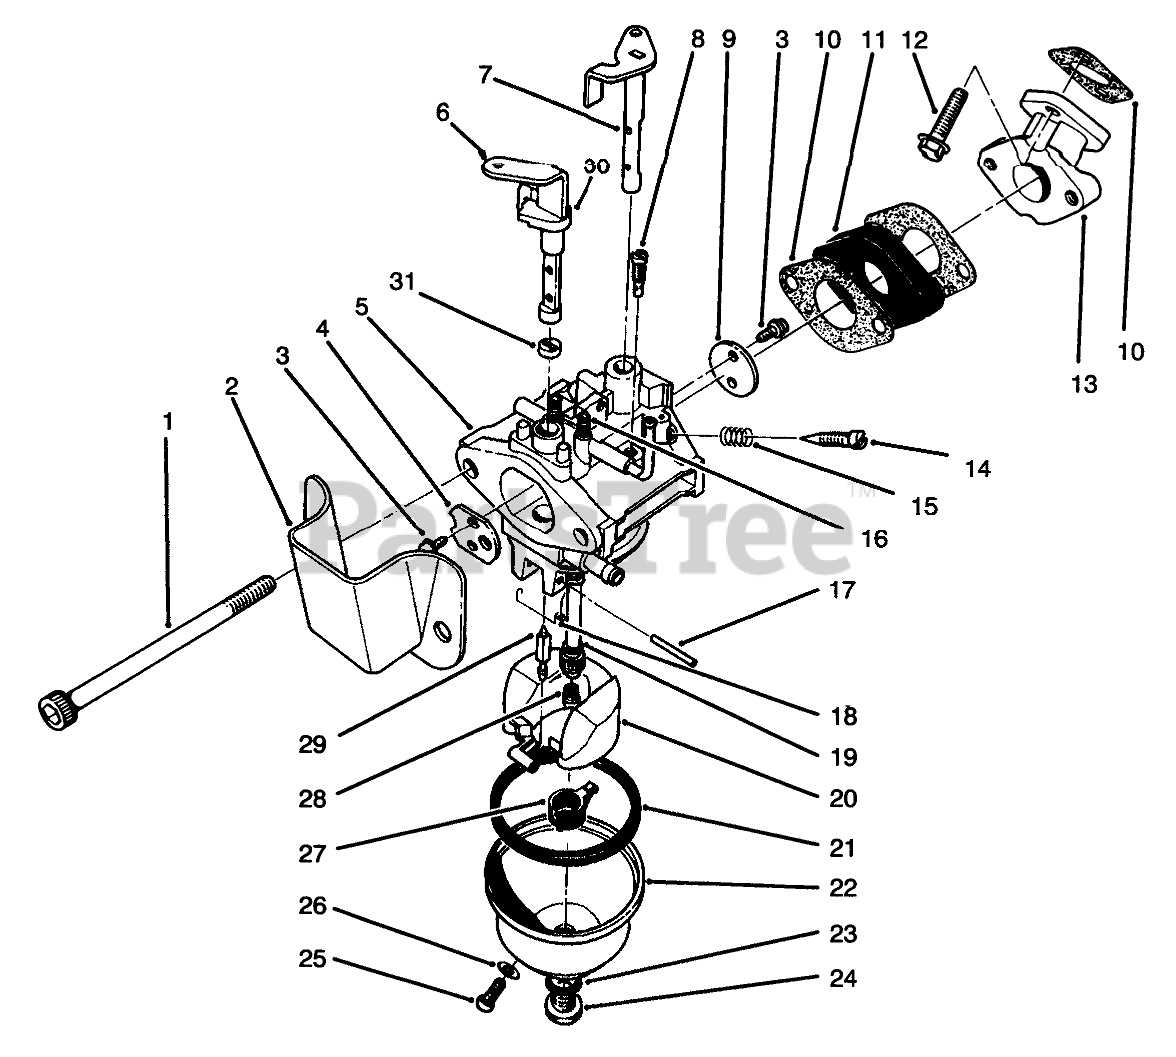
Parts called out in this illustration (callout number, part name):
2	SPIT CUP
3	Screw
4	VALVE
5	Body-Carburetor
6	Shaft-Choke (Incl. Ref. #30 & 31)
7	SHAFT
9	VALVE
10	Gasket-Carburetor
11	CARB INSULATOR
13	MANIFOLD
14	ADJUSTER
15	SPRING-PILOT SCREW
16	SPRING
17	PIN-HINGE
18	TORSION SPRING
19	MAIN NOZZLE
20	FLOAT
21	FLOAT BOWL GASKET
23	GASKET
24	SCREW
25	SCREW
26	GASKET
27	SPACER
28	MAIN JET
29	NEEDLE
30	UPPER CHOKE RING
31	LOWER CHOKE RING
